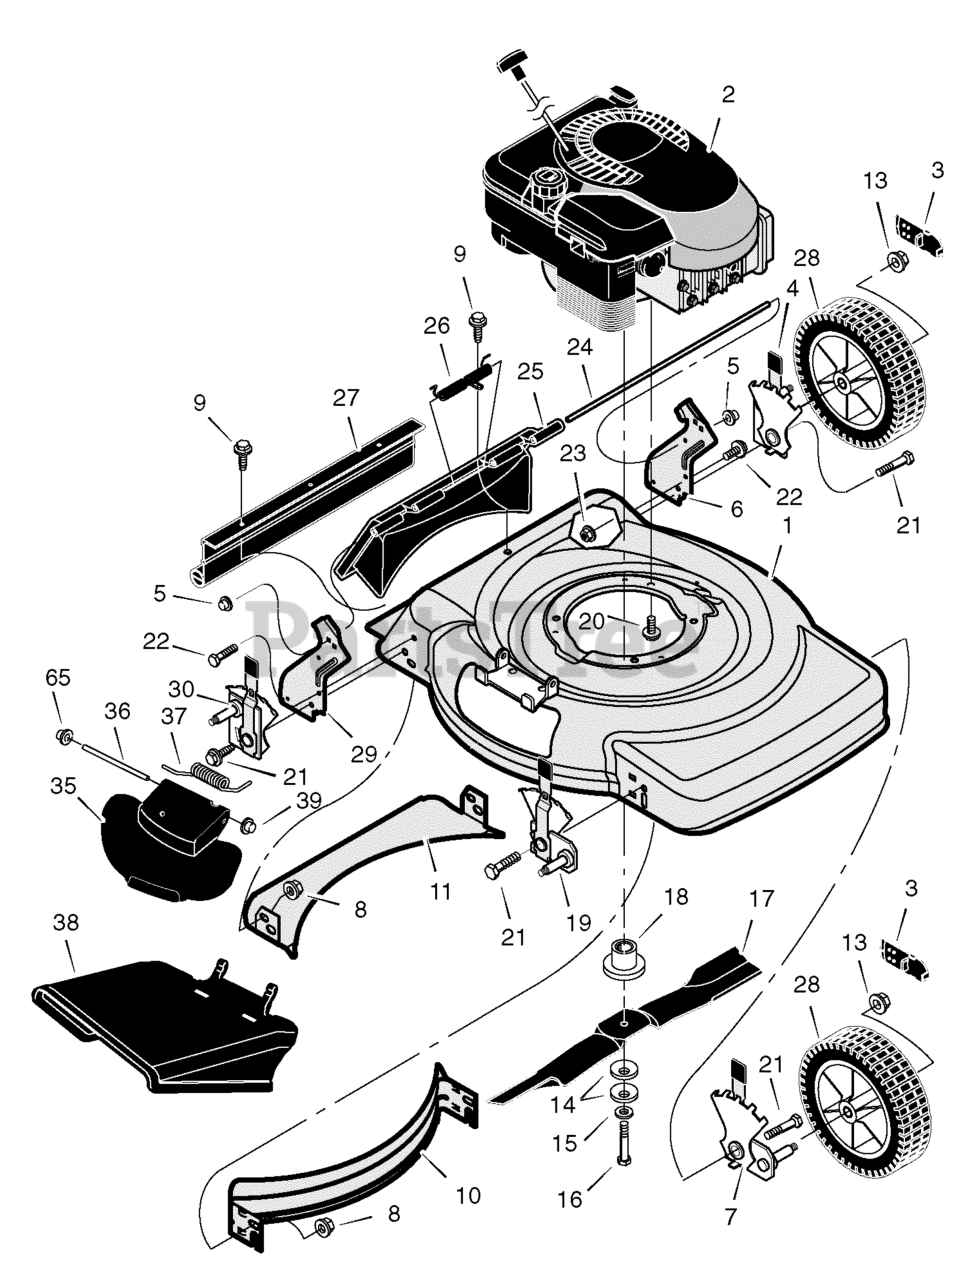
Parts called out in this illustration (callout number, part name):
1	Housing
2	Engine *
3	Cap, Hub (Optional)
4	Adjuster, Left Rear Height
5	Push On Cap
6	Bracket, Left Handle
7	Adjuster, Left Front Height
8	Nut, Flange
10	Baffle, Front
11	Baffle, Rear
13	Nut, Flange
14	Washer, Belleville
15	Washer
18	Adapter, Blade
19	Adjuster, Right Front Height
20	Bolt, Engine
22	Bolt
23	Nut, Flange
24	Rod, Pivot
25	Door, Rear (Black)
25	Door, Rear (Gray)
26	Spring
27	Guard, Rear
28	Wheel & Tire *
29	Bracket, Right Handle
30	Adjuster, Right Rear Height
35	Cover, Mulch (Black)
35	Cover, Mulch (Gray)
36	Rod, Pivot
37	Spring, Torsion
38	Deflector, Chute (Black)
38	Deflector, Chute (Gray)
39	Push On Cap
